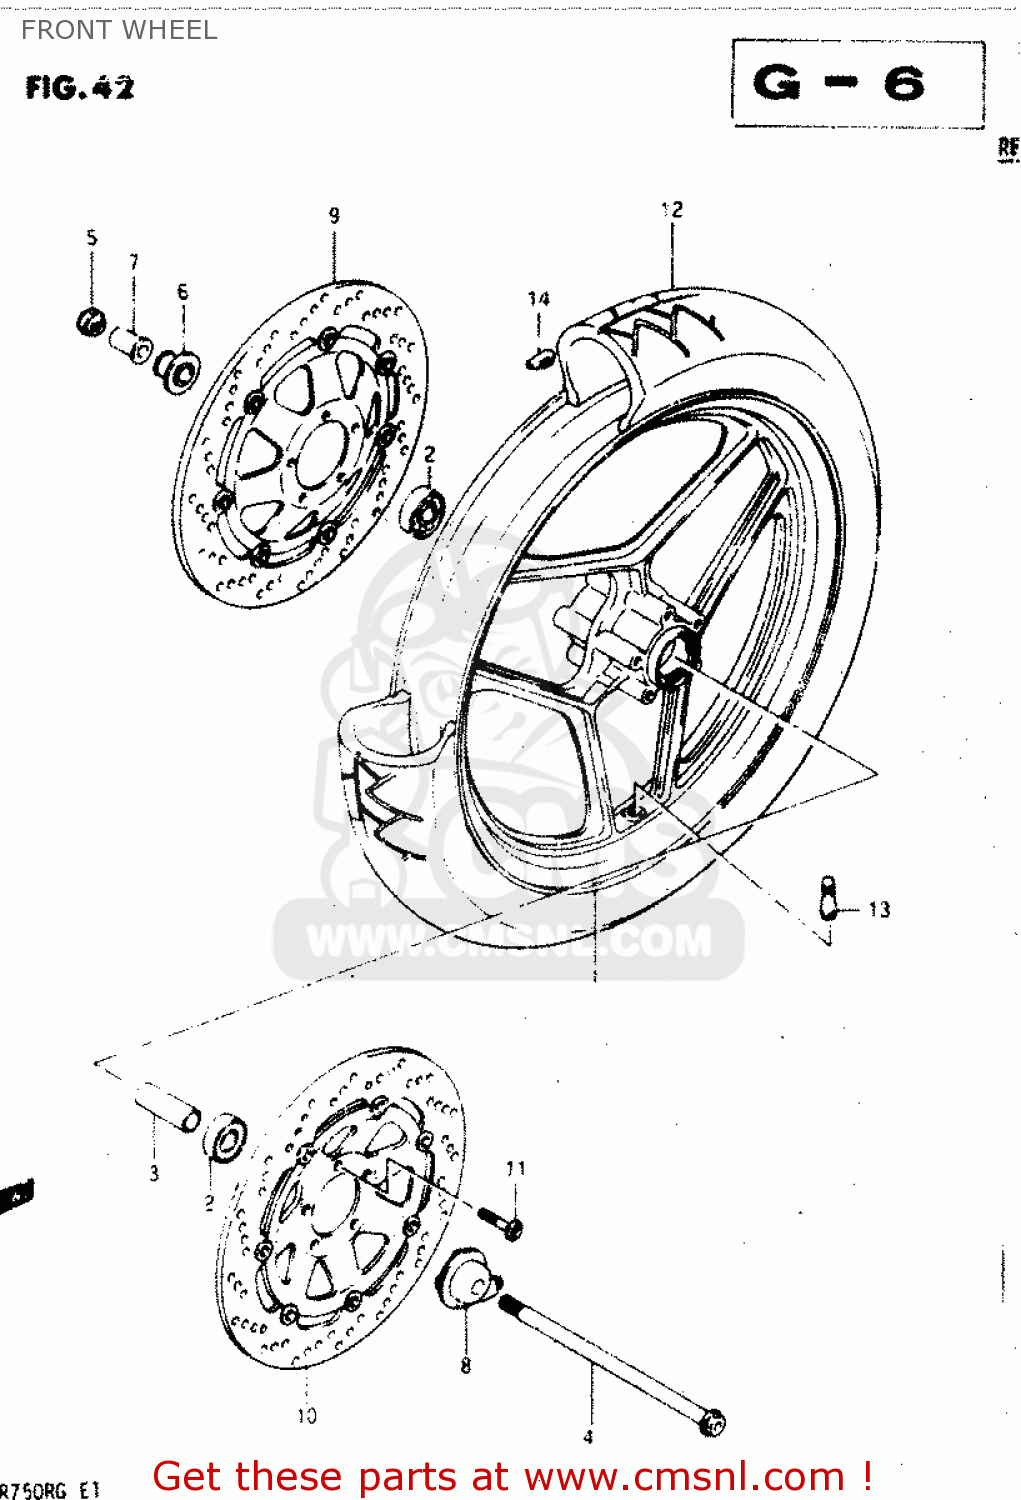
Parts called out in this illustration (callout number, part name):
1	WHEEL,FRONT
2	3
3	SPACER
4	AXLE, FRONT
5	NUT
6	SPACER,FR HUB BEARING,R
7	SPACER
8	BOX ASSEMBLY,SPEEDOMETER GEAR
9	DISC,BRAKE
10	DISC,BRAKE
11	BOLT
12	TIRE, T/L FRONT (110/80V-18)
13	VALVE,TIRE
14	BALANCER,WHEEL
